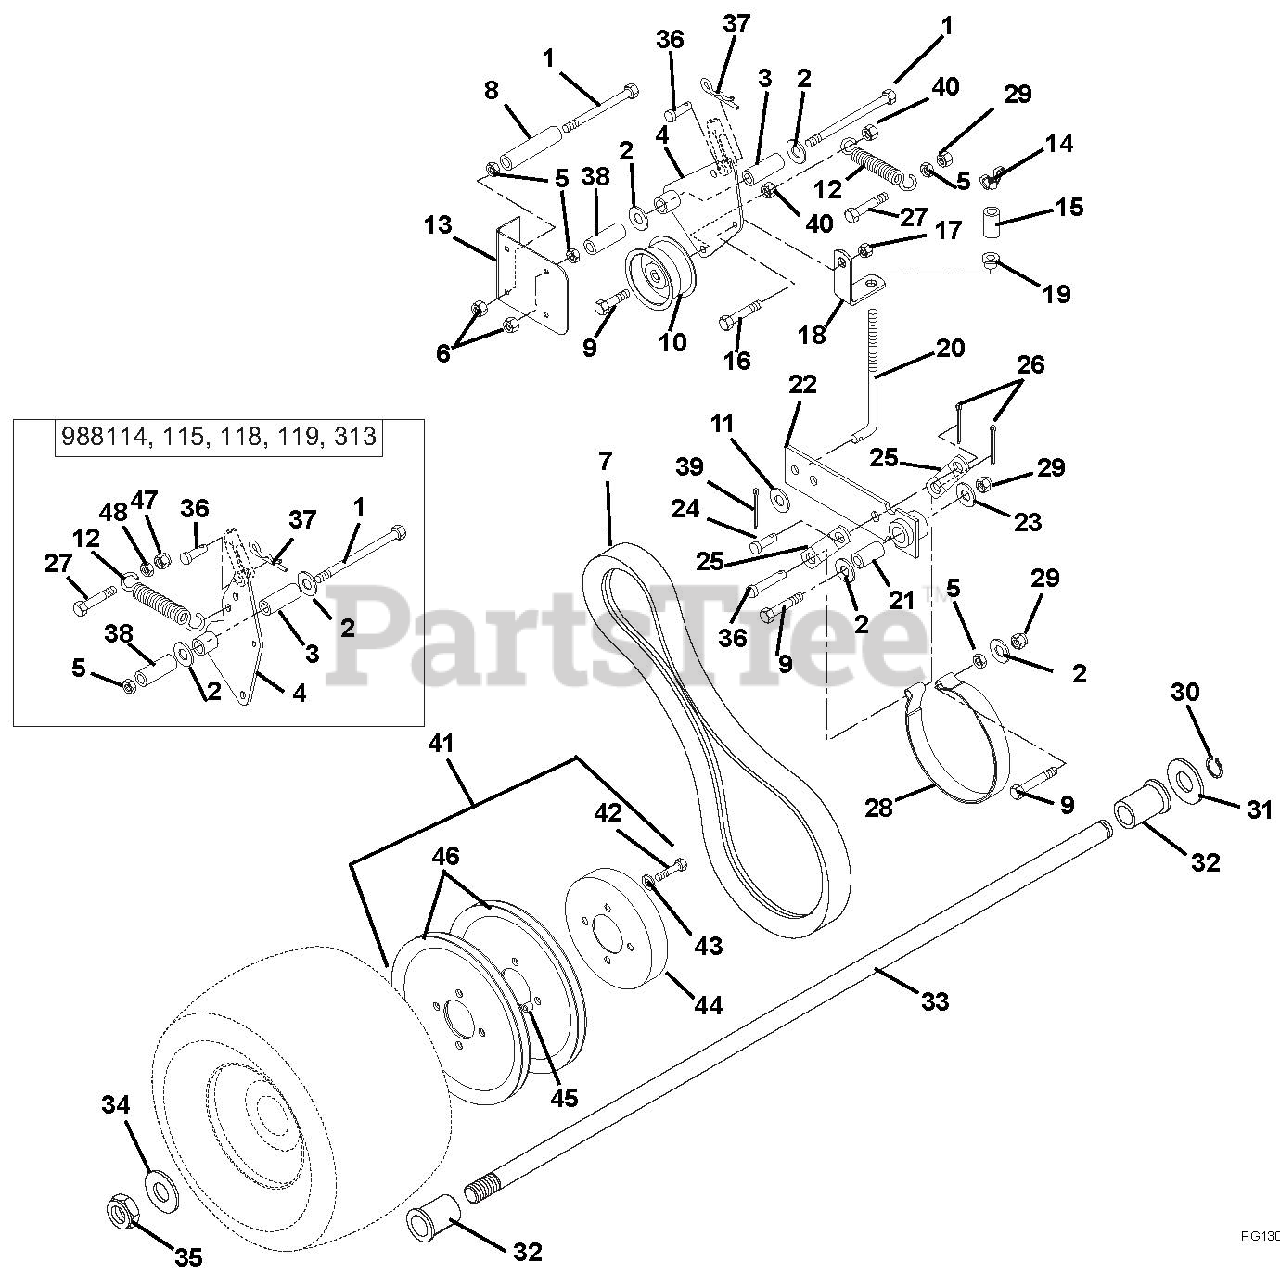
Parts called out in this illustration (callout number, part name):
1	Bolt-Hex .38-16 x 4.50 Grade 5
2	Washer-Flat-Steel .406 x .812 x .065
3	Bushing, Steel .385 x .610 x 1.80
4	Weldment- Wheel Clutch Arm
5	Nut-Hex .38-16
6	Nut-Locking-Flange .375-16
7	Belt, Traction Drive
8	Bushing, Spacer, 3.25 x .38 I.D. x .63 O.D.
9	Bolt-Hex .38-16 x 2.00 Grade 5
10	Sheave 3.25 x 1.25
11	Washer-Flat-Steel .344 x .688 x .065
12	Spring-Tension .105 x 1.00 x 5.00
13	Kit-Belt Cover with Decals
14	Nut-Nylock Wing .31-18
16	Bolt-Hex .25-20 x .75 Grade 5
17	Nut-Locking-Nylon .25-20
18	Bracket, Brake Link
19	Bushing-Flange .32 x .62 x .312 Nylon
20	Rod, Brake
21	Bushing Sleeve .39 x .622 x .95 Steel
22	Weldment, Brake Arm
23	Washer-Flat-Steel .406 x 1.00 x .188
24	Pin-Clevis .38 x .75
25	Link, Brake Arm
26	Pin-Cotter .12 x .75
27	Bolt-Hex .38-16 x 1.50 Grade 5
27	Bolt-Hex .31-18 x 2.00 Grade 5
28	Assembly, Pro Brake Band
29	Nut-Locking-Nylon .38-16
30	Ring-Retaining-External .906 x .078
31	Washer-Flat-Steel 1.01 x 1.50 x .062
32	Bushing-Flange 1.01 x 1.38 x 1.4 x 1.65
33	Shaft, Axle
34	Washer-Flat-Steel .812 x 1.50 x .135
35	Nut-Locking-Jam-Nylon .75-10
36	Pin-Clevis .38 x 1.25
37	Pin-Hair Internal .08 x .18 x 1.18
38	Bushing, Spacer
39	Pin-Cotter .09 x .75
40	Nut-Locking-Jam-Center .38-16
41	Assembly, Pulley and Drum
42	Bolt-Hex .31-18 x 1.50 Grade 5
43	Washer-Locking .31 x .078 Regular
44	Drum, Brake
45	Bushing, Sleeve .385 x .625 x .475 Steel
46	Sheave 8"
47	Nut-Locking-Center .31-18
48	Nut-Hex .31-18
